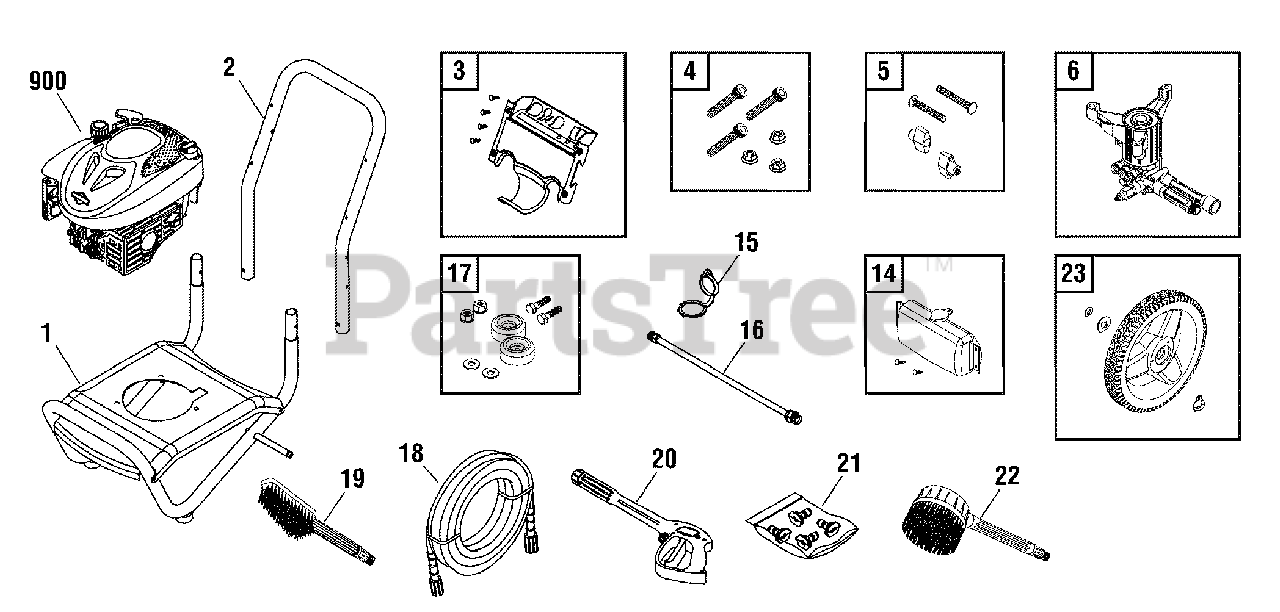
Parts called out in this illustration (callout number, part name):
2	HANDLE
4	KIT, Hardware, Pump Mounting
5	KIT, Hardware, Handle
6	PUMP
15	CAP, Chemical Tank
16	EXTENSION, QC
17	KIT, Vibration Mount
18	HOSE, 25’
20	GUN
21	KIT, QC Nozzles
22	BRUSH, Rotating
900	* ENGINE
